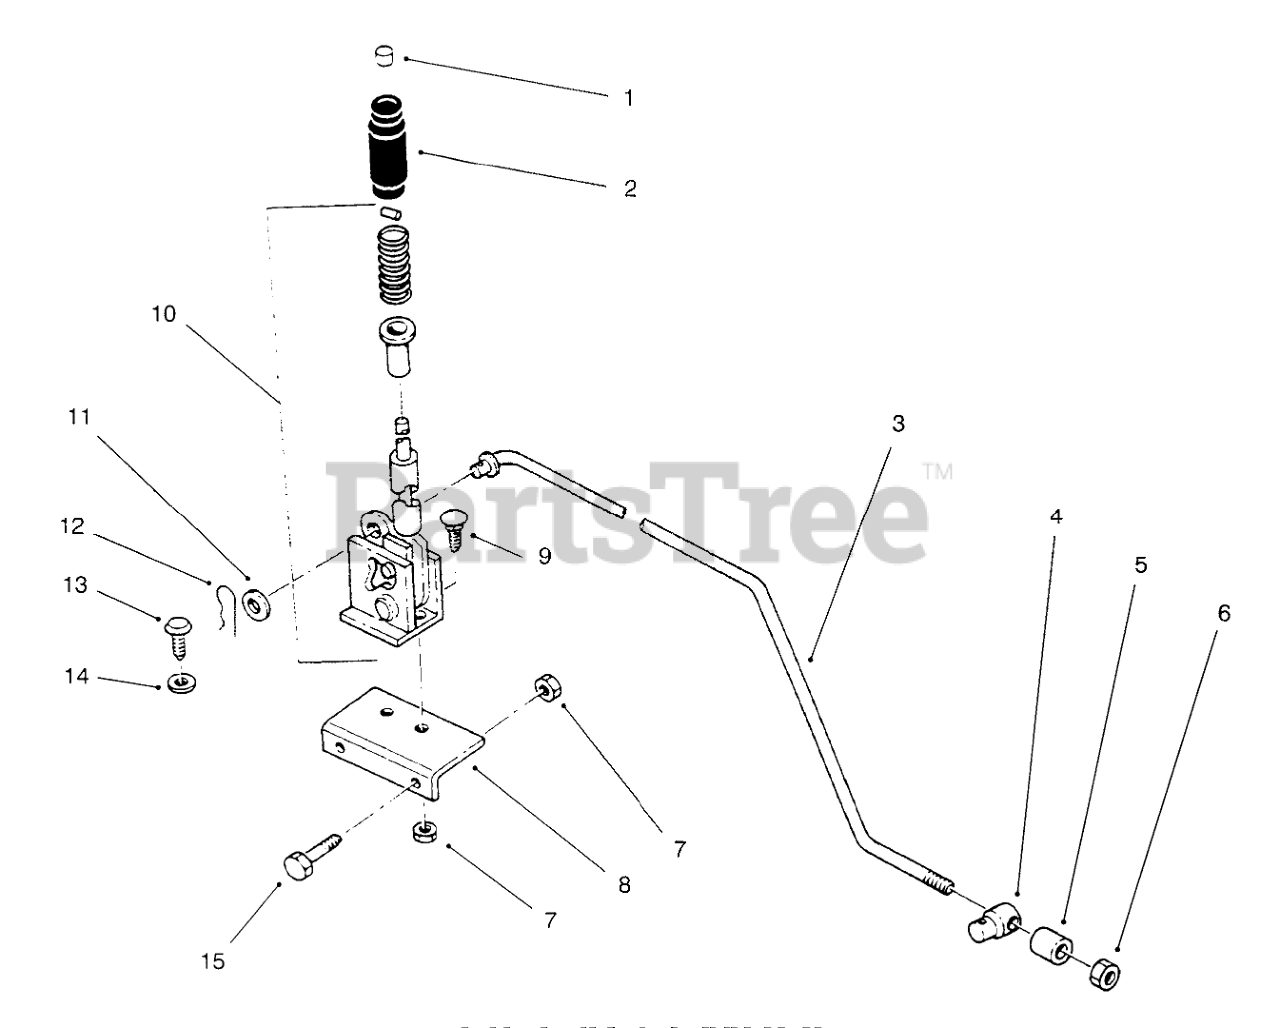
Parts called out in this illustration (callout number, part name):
1	CAP-ROD, PLUNGER
2	HANDGRIP
3	LIFT ROD ASM
4	TRUNION
5	SPACER-ROLLER
6	NUT-LOCK, NI
7	NUT-LOCK, NI
8	Bracket-Support
9	BOLT-CARR
10	Handle-Lift
11	WASHER-FLAT
12	Hairpin
13	FOOTPAD FASTENER
14	WASHER-FLAT
15	SCREW-HH
